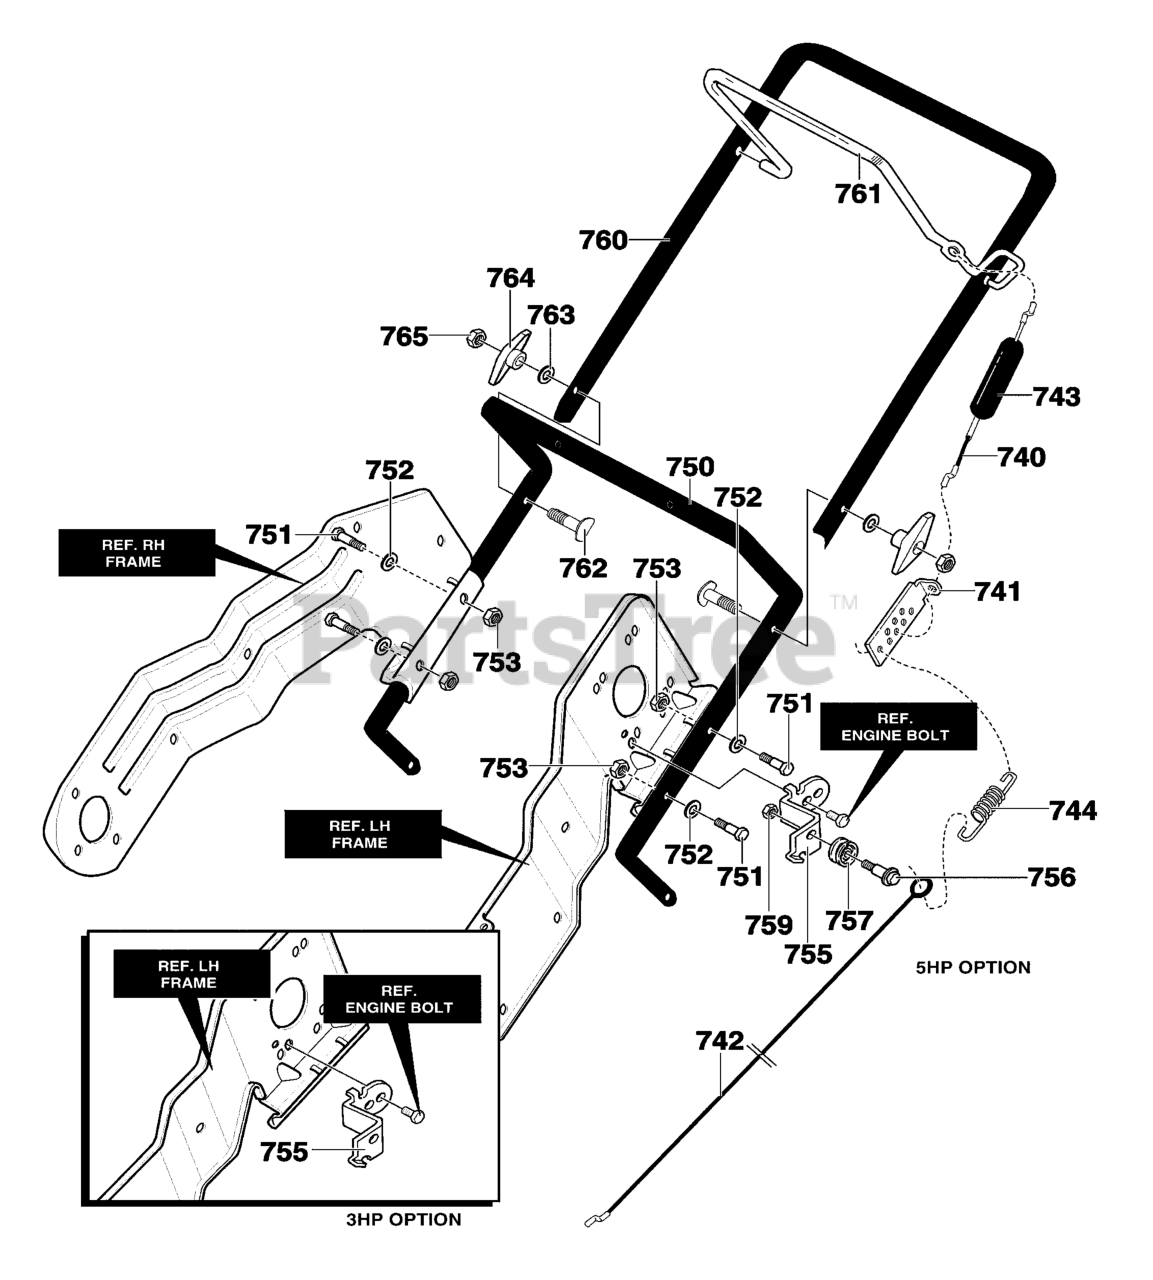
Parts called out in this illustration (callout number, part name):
740	CABLE, UPPER
741	BRACKET, CABLE ADJ
742	CABLE LOWER CONTROL
743	BOOT, CLUTCH SPRING
750	HANDLE LOWER
751	SCREW, 1/4-20X1.25
752	WASHER, FLAT
753	NUT, 1/4-20
755	BRACKET, CABLE
757	PULLEY
759	NUT, 1/4-20
760	HANDLE, UPPER
761	BAIL, CONTROL
762	BOLT, 5/16-18X2.00
763	WASHER, FORM
764	KNOB, T
765	NUT, 5/16-18
